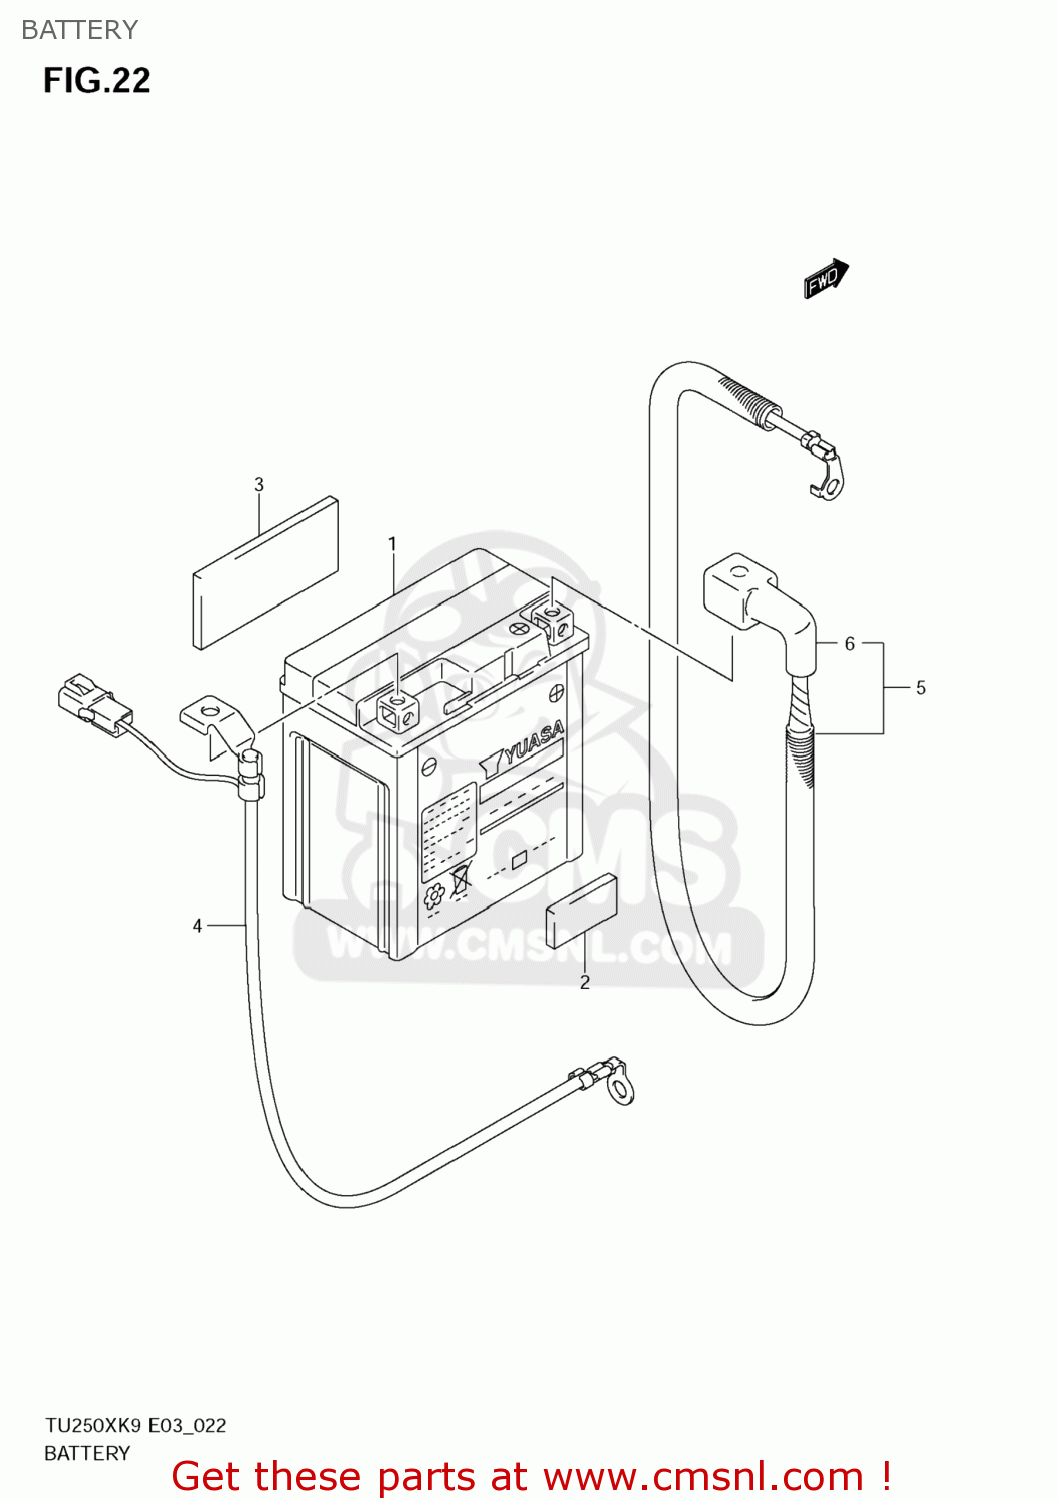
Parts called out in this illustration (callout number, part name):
1	BATTERY ASSY(YTX7L-BS,12V6AH)
2	PROTECTOR,BATTERY(100X70X3)
3	PROTECTOR(170X95X3.0)
4	WIRE,BATTERY MINUS LEAD
5	WIRE,BATTERY PLUS LEAD
6	CAP,BATTERY PLUS TERMINAL
